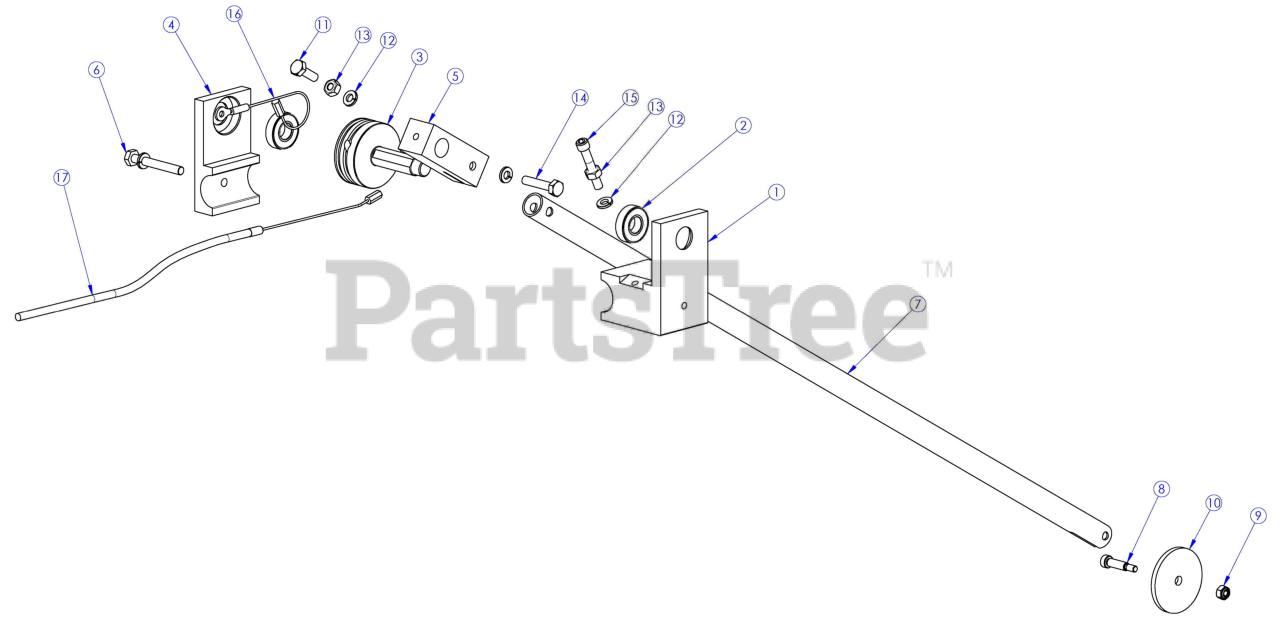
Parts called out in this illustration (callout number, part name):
1	Block, Guide Arm Mount
2	Bearing, .500 Id, R8-2Rs
3	Pulley, Guide Arm
4	Block, Pulley Mount
5	Guide Arm Mounting Block
6	HHB 1/4-20 X 2 S.S. All Thrd
7	Tube, Guide Arm
8	Shsb, 1/4 X 3/4
9	Nut, Nyloc, #10-24 Cad
10	Wheel, Guide
11	HHB 1/4-20 X .75 S.S.
12	Washer, Split 1/4" S.S.
13	Nut, 1/4-20 Hex, S.S.
14	HHB 1/4-20 X 1.25 S.S. All Thrd
15	Shcs 1/4-20 X 1 1/2 S.S.
16	Cable, Guide Arm Return
17	Cable, Guide Arm
